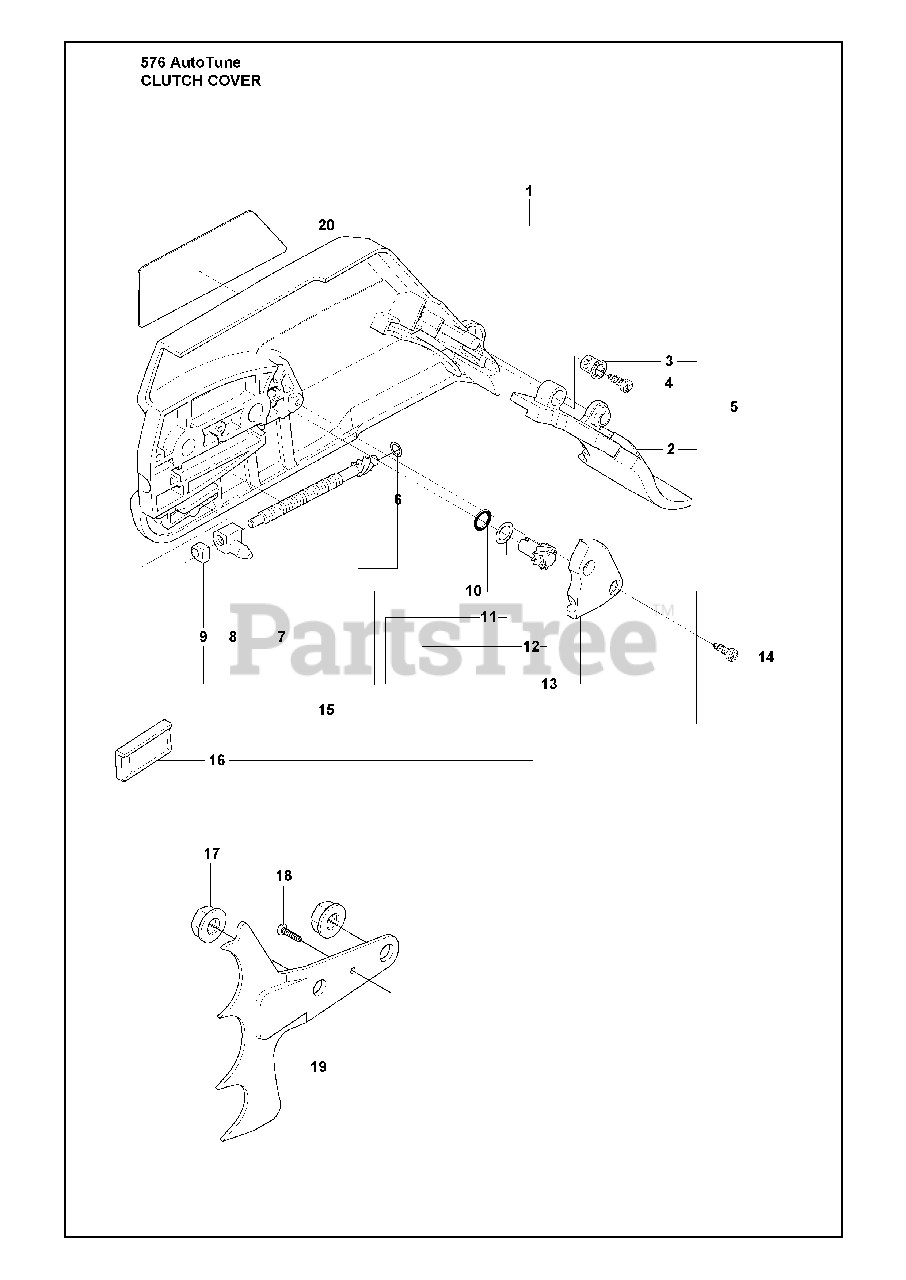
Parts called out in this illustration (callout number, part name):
1	CLUTCH COVER ASSY
5	CLUTCH COVER ASSY H SILVER R-
7	ADJUSTER
12	RP ADJUSTER
15	KIT-CHAIN TENSIONER
16	CHAIN GUIDE
17	NUT M8 FLANGE
19	SPIKE OUTER
